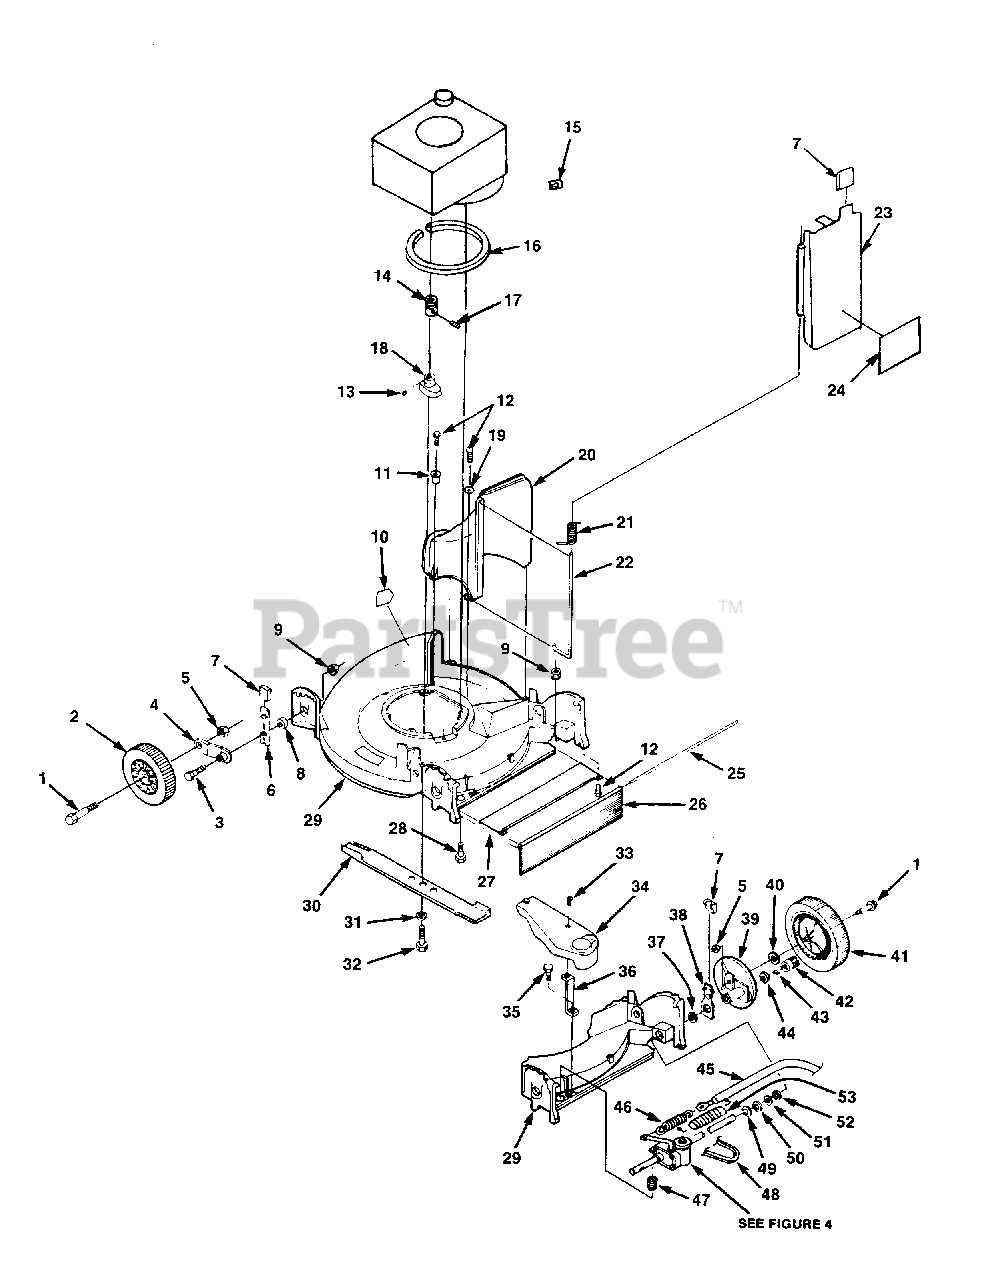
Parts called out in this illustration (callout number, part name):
1	BOLT- Axle 3/8-16
2	WHEEL & TIRE Push W/B Wheels
3	BOLT- Hex hd. hgt. adj. 5/16-18
4	ARM- Wheel hgt. adjusting
5	NUT- Hex 3/8-16
6	SPRING- Index
7	KNOB- Index spring
8	SPACER- Height adj.
9	NUT- Flange 5/16-18
10	DECAL- Warning
11	SIMPSON EYELET
12	SCREW- Hex hd. 1/4-20 x 3/4"
13	KEY- Woodruff #61
14	PULLEY- Drive
15	STOP- Rope
16	RING- Engine
17	SCREW- Set 1/4-20 x 3/8"
18	ADAPTER- Blade
19	WASHER- Plain 1/4"
20	CHUTE- Discharge
21	SPRING- Chute door
22	PIN- Hinge
23	DOOR- Chute
24	DECAL- Door
25	ROD- ZP Drag flap
26	FLAP- Drag
27	COVER- Rear
28	SCREW- 3/8-16 x 1 1/2"
29	DECK- 21"
30	BLADE- 21"
31	WASHER- Lock hvy. 3/8"
32	SCREW- 3/8-24 x 1 1/4"
34	COVER- Drive
35	SCREW- Hex hd. 10-16 x 1/2"
36	SUPPORT- Belt cover
37	SPACER- Rear hgt. adj.
38	SPRING- Index
39	DRIVE WHEEL SUPPORT
40	WASHER- Flat
41	WHEEL & TIRE (Drive)
42	PINION (R.H.)
43	PAWL- Pinion HT
44	WASHER- Flat
45	CABLE- Traction Contr.
46	SPRING- Traction lever
47	SPRING- Compression
48	BELT- Drive
49	RING- Eaton
51	WASHER- Shim
52	WASHER- Flat
53	COVER- Spring
